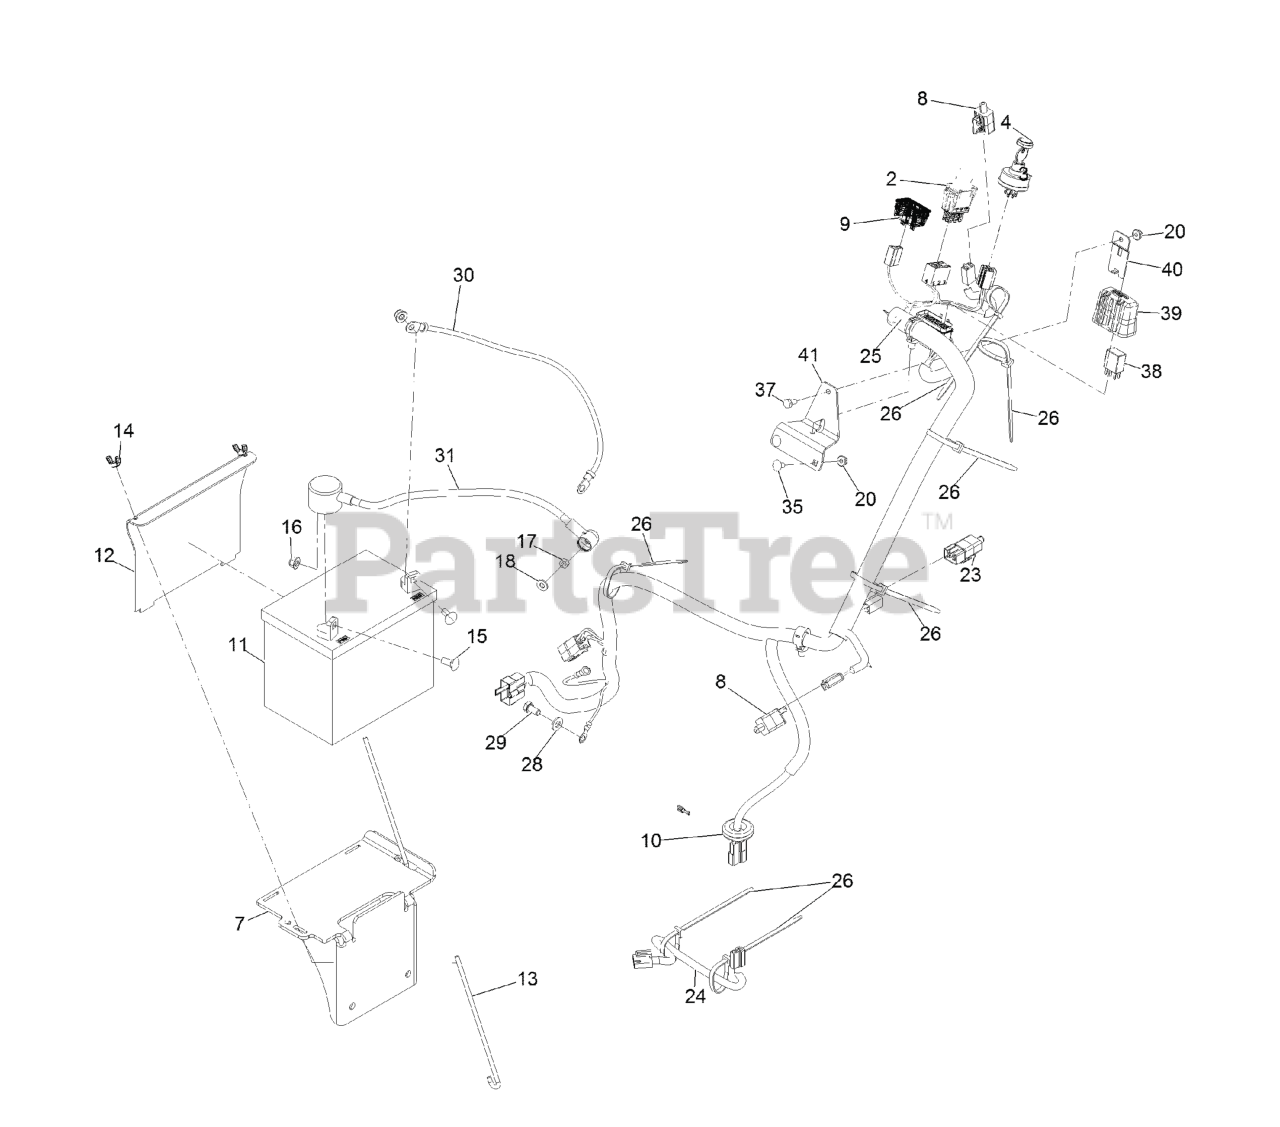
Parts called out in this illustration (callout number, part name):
2	SWITCH-PTO
3	SWITCH, KEY START
4	NUT-SWITCH, IGNITION
7	WELD, BATTERY MOUNT
9	METER-HOUR
10	GROMMET
11	Battery
12	BRACKET, BATTERY HOLD DOW
13	BOLT-HOLDDOWN
14	WINGNUT
15	BOLT-CARR
16	NUT-HF, NI
17	NUT-HEX
18	WASHER-FLAT
23	SWITCH, 2 POLE
24	HARNESS-CLUTCH PIGTAIL
25	HARNESS-WIRING
26	TIE-PLASTIC
28	WASHER-PLAIN
29	SCREW-HH
31	ASM,POSITIVE BATTERY CABL
35	SCREW-CARR
37	SCREW-HH
38	RELAY-MICRO 280, SPDT
39	COVER-BLOCK, FUSE
40	CLIP-MOUNTING
41	BRACKET-MOUNTING, FUSEBLO
